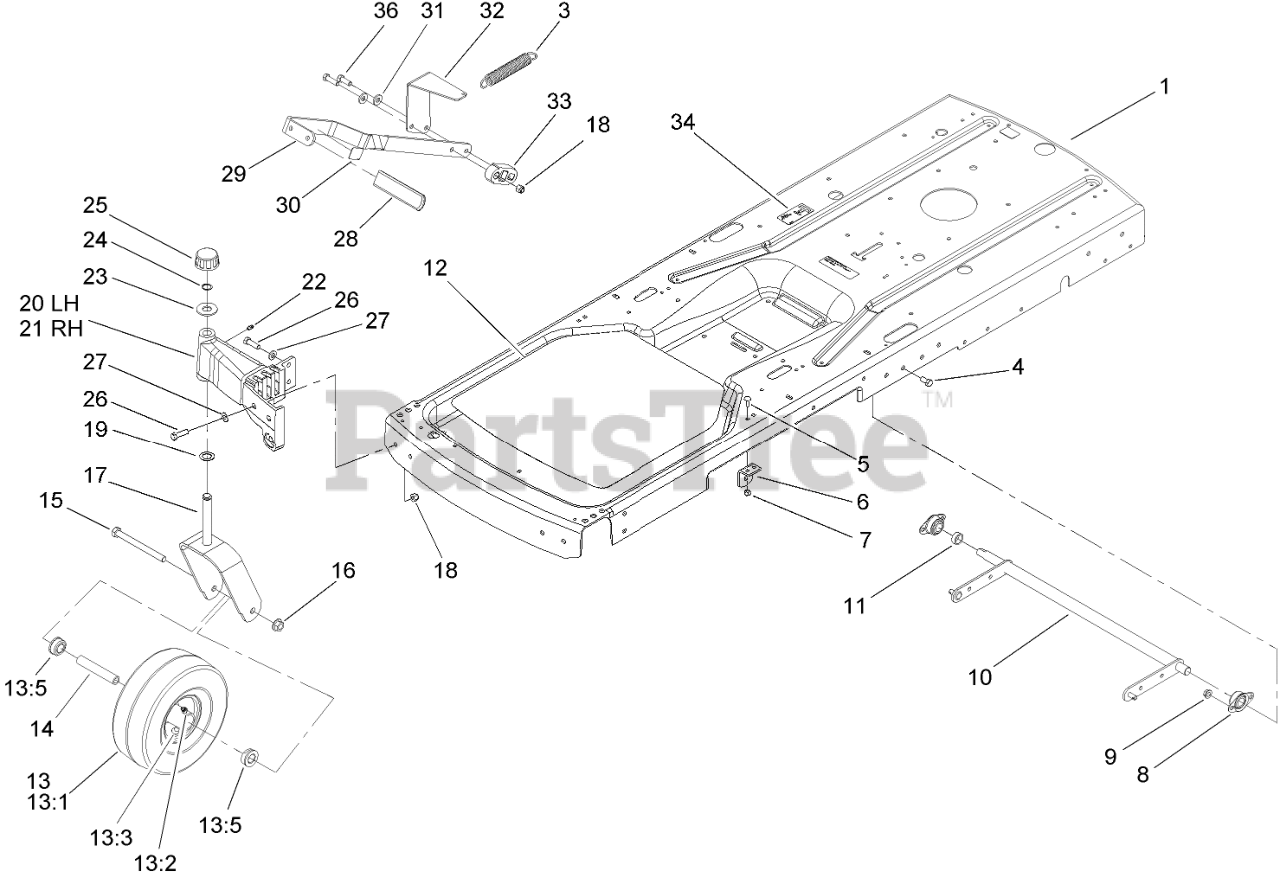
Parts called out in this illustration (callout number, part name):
3	SPRING-EXTENSION
4	SCREW-HH
5	BOLT-CARR
6	BRACKET-LIFT
7	NUT-LOCK, NI
8	BEARING-FLANGE, SIDE
9	NUT-HHF, WHIZ
10	LIFT ARM ASM
11	SPACER
12	PAD-ANTISKID
13	FRONT WHEEL AND TIRE ASM
13:2	FITTING-GREASE
13:3	STEM-VALVE
13:5	BUSHING-FLANGE
14	BUSHING-SPANNER
15	SCREW-HH
16	NUT-HF
17	CASTOR FORK ASM
18	NUT-LOCK, NI
19	WASHER-THRUST
20	CASTER-LH
21	CASTER-RH
22	FITTING-GREASE
23	WASHER-PLAIN
24	RING-RETAINING, EXT
25	CAP-HUB
26	SCREW-HH
27	WASHER-FLAT
28	GRIP-LEVER, LIFT
29	LEVER-LIFT
30	DECAL-HOC
31	WASHER-BELLEVILLE
32	MOUNT-SPRING, FRONT
33	BLOCK-LIFT
34	DECAL-TRANSPORT, CE
36	SCREW-HH
